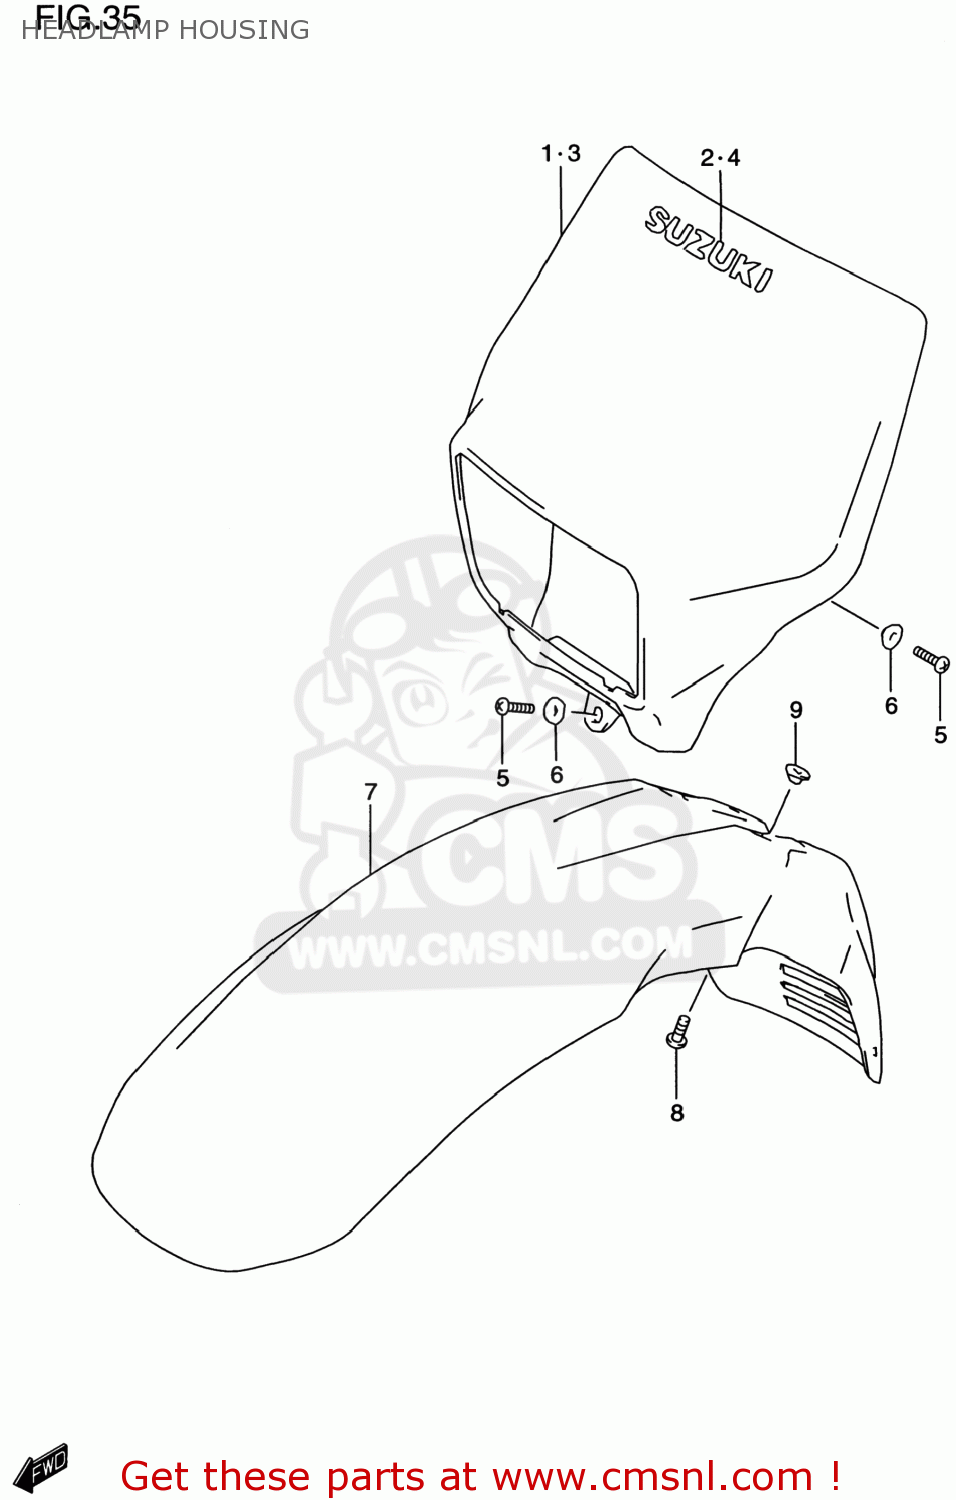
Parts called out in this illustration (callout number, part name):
1	COVER,HEADLAMP
2	EMBLEM
3	COVER,HEADLAMP
4	EMBLEM,SUZUKI
5	SCREW 6X12
6	WASHER
7	FENDER,FR
8	BOLT(6X16)
9	WASHER
